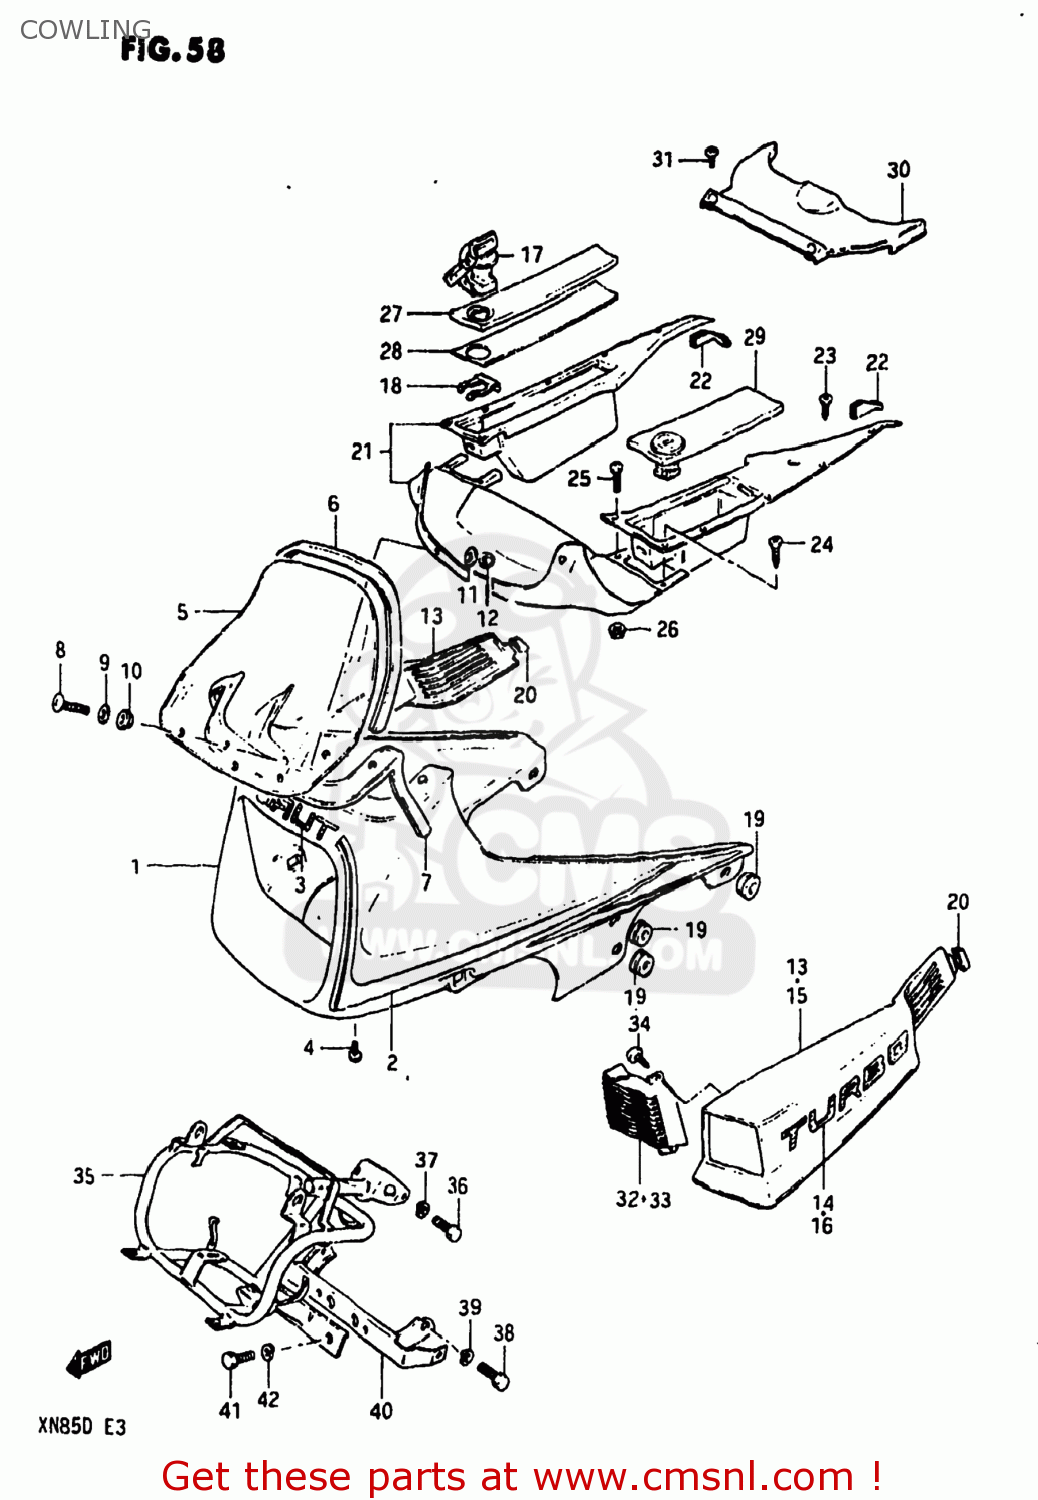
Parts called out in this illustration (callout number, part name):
1	COWLING ASSEMBLY
2	TAPE SET,COWLING
3	EMBLEM,COWLING,FRONT
4	SCREW 6X12
5	WINDSCREEN
6	MOLDING
7	CUSHION,COWLING WINDOW
8	(5X20) CROSS SCREW
9	WASHER(5.2X11X1)
10	SPACER,COWLING WINDOW
11	WASHER
12	NUT
13	COVER,COWLING,RIGHT
14	EMBLEM,COVER SIDE
15	COVER,COWLING,LEFT
16	EMBLEM,COVER SIDE
17	LOCK,CONSOLE BOX
18	LOCK,HOLDER
19	CUSHION
20	CUSHION,COWLING COVER
21	PANEL,COWLING,UPPER
22	CUSHION
23	SCHROEF 4X12
24	SCREW
25	SCREW
26	NUT
27	COVER,TOOL BOX
28	SEAL,TOOL BOX COVER
29	COVER,FUSE BOX
30	INNER COVER,COWLING
31	SCREW
32	DUCT,COVER COWLING,RIGHT
33	DUCT,COVER COWLING,LEFT
34	SCREW
35	BRACE,COWLING
36	BOLT
37	LOCK WASHER
38	BOLT 8X12
39	LOCK WASHER
40	BRACE
41	BOLT
42	LOCK WASHER
